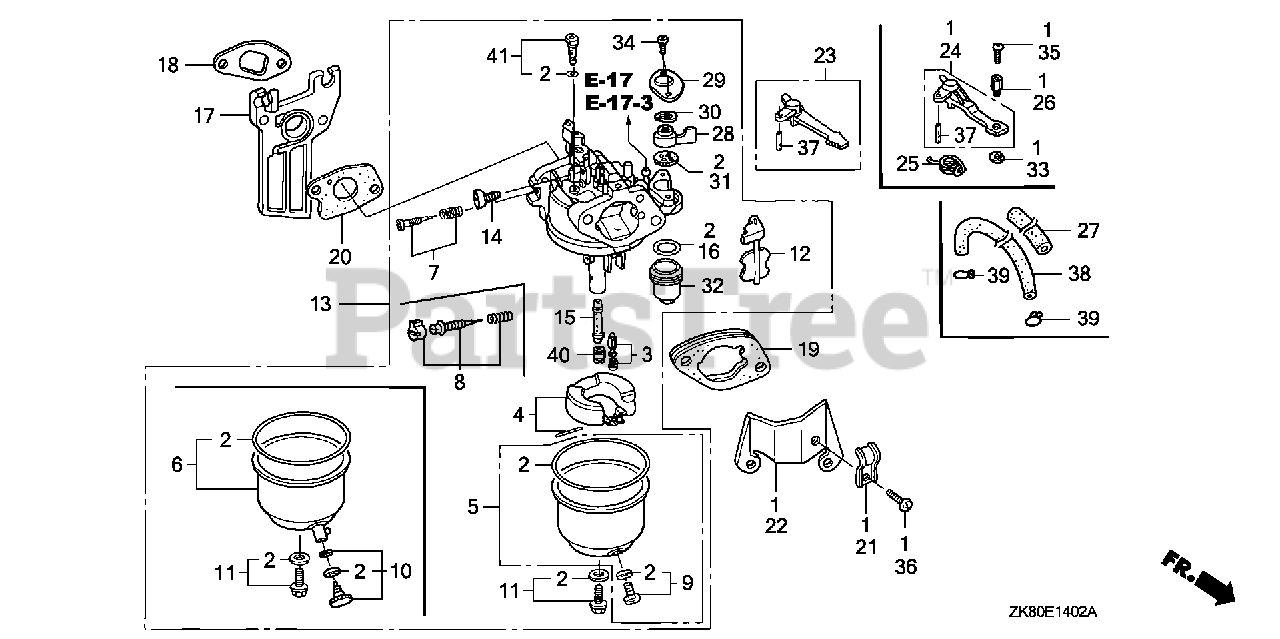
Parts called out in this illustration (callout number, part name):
2	GASKET SET
3	VALVE SET, FLOAT (SEAT NOT INCLUDED)
5	CHAMBER SET, FLOAT
8	SCREW SET, PILOT (CARBURETOR NO.)
9	SCREW SET, DRAIN
11	SCREW SET
13	CARBURETOR ASSY. (BE65B B/C)
14	SCREW, THROTTLE STOP
15	NOZZLE, MAIN
16	GASKET, FUEL STRAINER CUP
17	INSULATOR, CARBURETOR
18	GASKET, INSULATOR
19	SPACER, CARBURETOR
20	GASKET, CARBURETOR
23	LEVER, CHOKE (STD)
28	LEVER, PETCOCK
29	PLATE, LEVER SETTING
30	SPRING, PETCOCK LEVER
31	GASKET, PETCOCK
32	CUP, FUEL STRAINER
34	SCREW, PAN (3X6)
37	PIN, SPRING (2X12)
40	JET, MAIN (#65)
40	JET, MAIN (#68)
40	JET, MAIN (#70)
41	JET SET, PILOT (#35)
